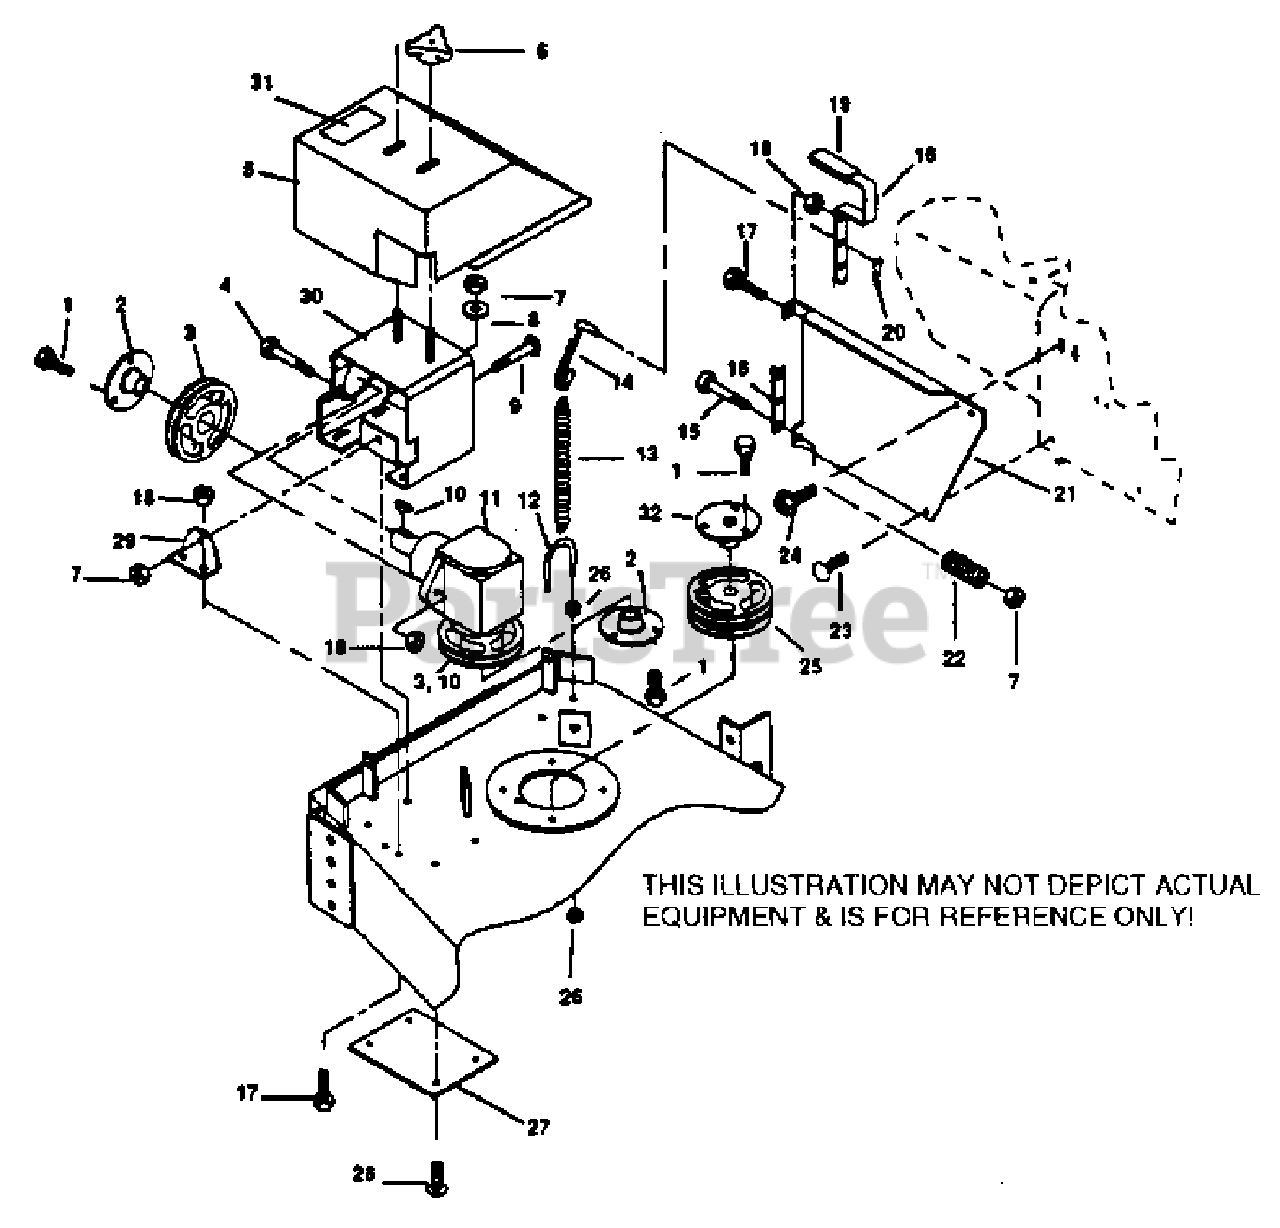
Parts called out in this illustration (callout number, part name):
2	TAPERED HUB, 5/8" BORE
3	PULLEY, 5.8" TAPERED BORE
4	CAPSCREW, 3/8-16 X 1-1/4" SER. FLG.
5	BELT COVER, W/DECAL
6	WINGNUT, 3/8-16 NON METALLIC
7	NUT, 3/8-16 ELASTIC STOP
8	FLAT WASHER, 3/8"
10	KEY, WOODRUFF #9, 3/16 X 3/4"
11	GEARBOX, 90 DEGREE DRIVE
12	U-BOLT, 5/16-18 X 2.19"
13	EXTENTION SPRING
14	ROD, COUNTER BALANCE
15	CARRIAGE BOLT, 3/8-16 X 1-1/2"
16	LEVER, COUNTER BALANCE
17	CAPSCREW, 3/8-16 X 3/4" SERR. FLANGE
18	NUT, 3/8-16 SERR. FLANGE HEX HEAD
19	GRIP, SHIFT LEVER
20	HAIR PIN, .094 X 1.62
21	MOUNTING BRACKET, COUNTER BALANCE
22	SPRING, COMPRESSION
24	CAPSCREW, 5/16-18 X 3/4" SERR. FLANGE
25	PULLEY, 5-3/4 DOUBLE GROOVE
26	NUT, 5/16" SERRATED FLANGE
27	REINFORCEMENT PLATE, GEARBOX
29	ANCHOR BRACKET, TENSION BOLT
30	SUPPORT WELDMENT GEAR BOX
31	DECAL, WARNING
32	TAPERED HUB, 1.00" BORE
